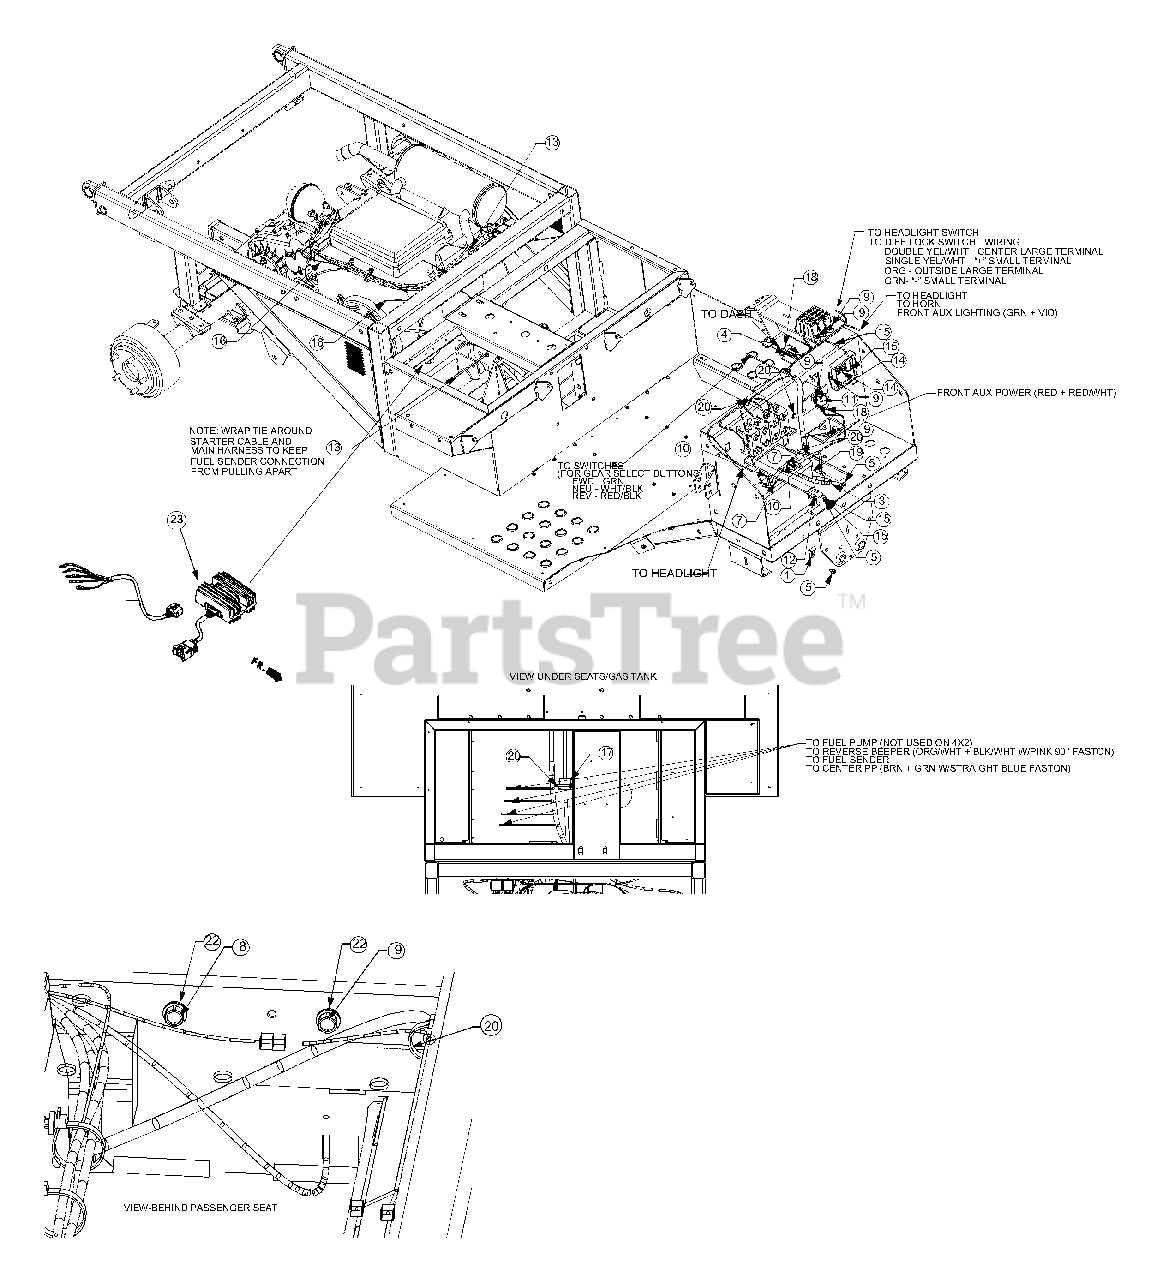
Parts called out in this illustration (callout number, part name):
1	Bracket, Retainer Hook
3	Harness Assembly, Motor Ground
4	Screw, 1/4-20 x .50
5	Screw, Self-tapping, 1/4-20 x 0.500
7	Screw, Hex Carriage, 1/4-20 x .75
8	Screw, Self-tapping, 1/4-20 x 1.000
9	Screw, #10-24 x 0.75
10	Nut, Hex Sems, 1/4-20
11	Cover, Protective
12	Strap, Battery
13	Cable Tie, 3/16 x .05 x 7.4
14	Control, Shaft
15	Harness, Utility Main
16	Harness, Motor
17	Control, Reverse
18	Switch
19	Battery
20	Cable Tie, .19 x 8.39 Tree Mount
22	Lock Washer, 1/4
23	Rectifier Assembly, Regulator (20A)
